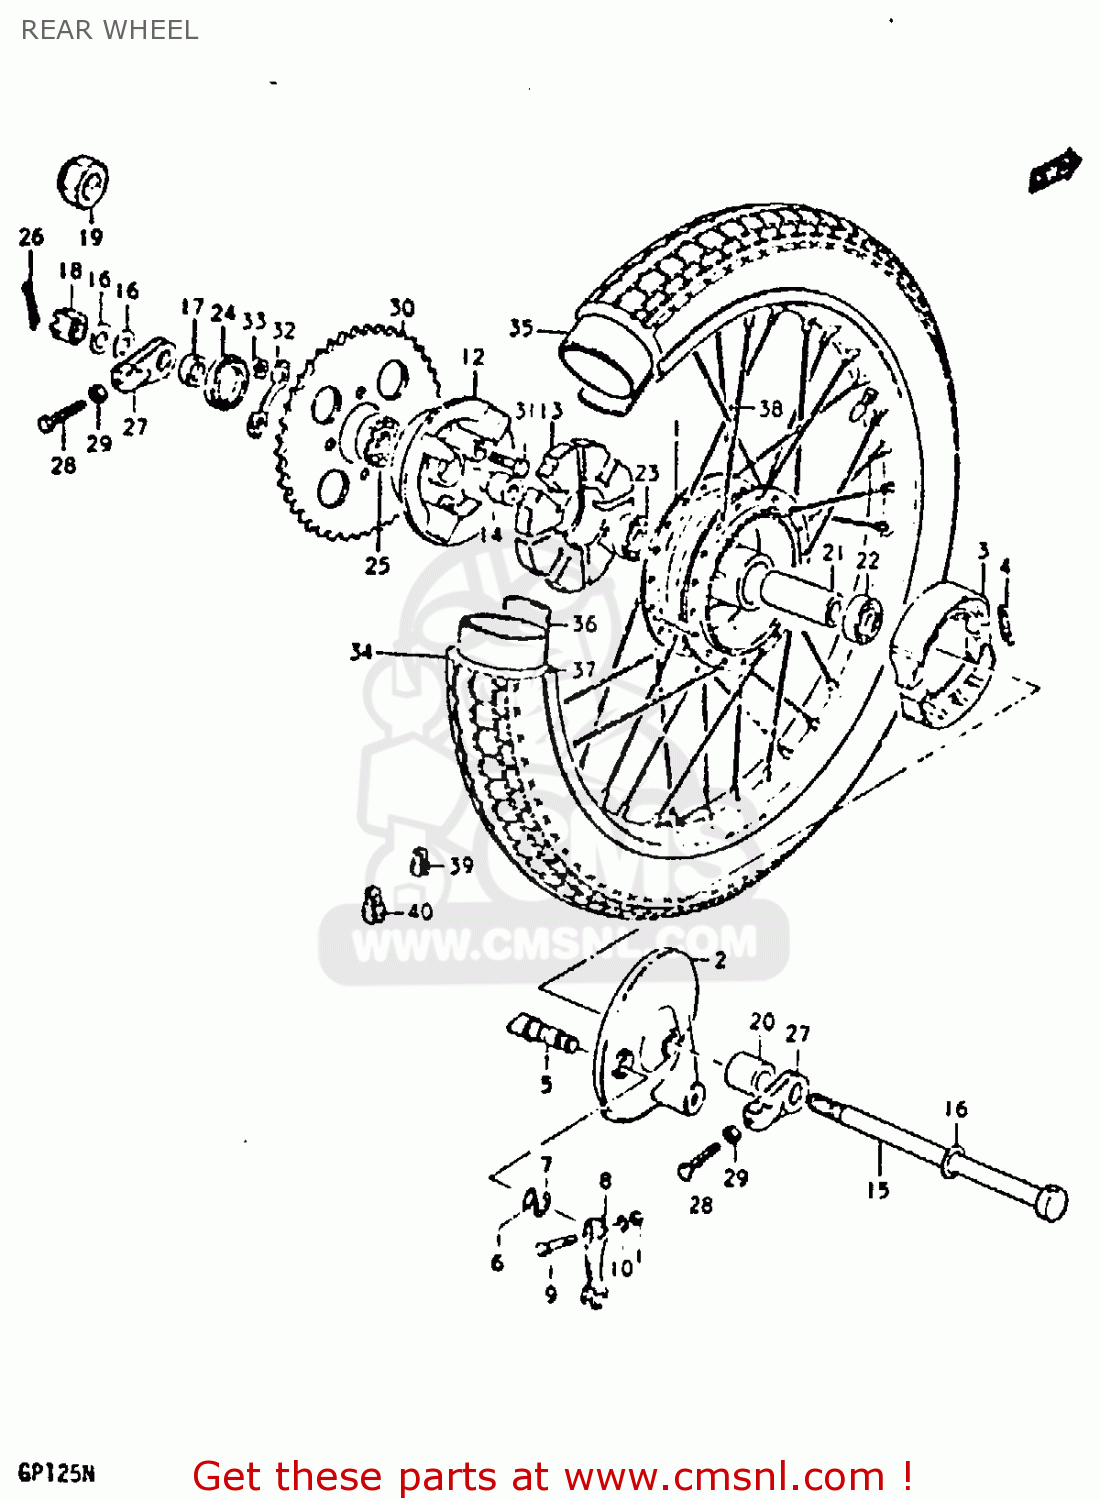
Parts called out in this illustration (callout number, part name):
1	HUB, REAR
2	PANEL, REAR HUB
3	SHOE,BRAKE
4	SPRING(L:34)
5	CAM,FRONT BRAKE
6	O-RING (D:2.4 ID:13.8)
7	WASHER (14.5X22X1.6)
8	LEVER,RR BRAKE CAM
9	BOLT(6X33)
10	WASHER
11	NUT
12	DRUM,RR SPROCKET
13	ABSORBER ASSY,HUB SHOCK
14	RETAINER,RR SPROCKET MTG
15	AXLE,REAR
16	WASHER
17	SPACER(15X28X19)
18	NUT
20	SPACER(15.2X26X33)
21	SPACER(15.3X21.7X63)
22	BEARING
23	BEARING
24	OIL SEAL
25	Bearing
26	COTTER PIN
27	ADJUSTER,CHAIN
28	BOLT
29	NUT
30	SPROCKET,REAR
31	BOLT(8X33.5)
32	WASHER
33	NUT
34	TIRE
35	TUBE,INNER
36	PROTECTOR,INNER TUBE
37	RIM,REAR WHEEL
38	SPOKE SET,REAR
39	BALANCER,WHEEL (B)
40	BALANCER,WHEEL (30G)
